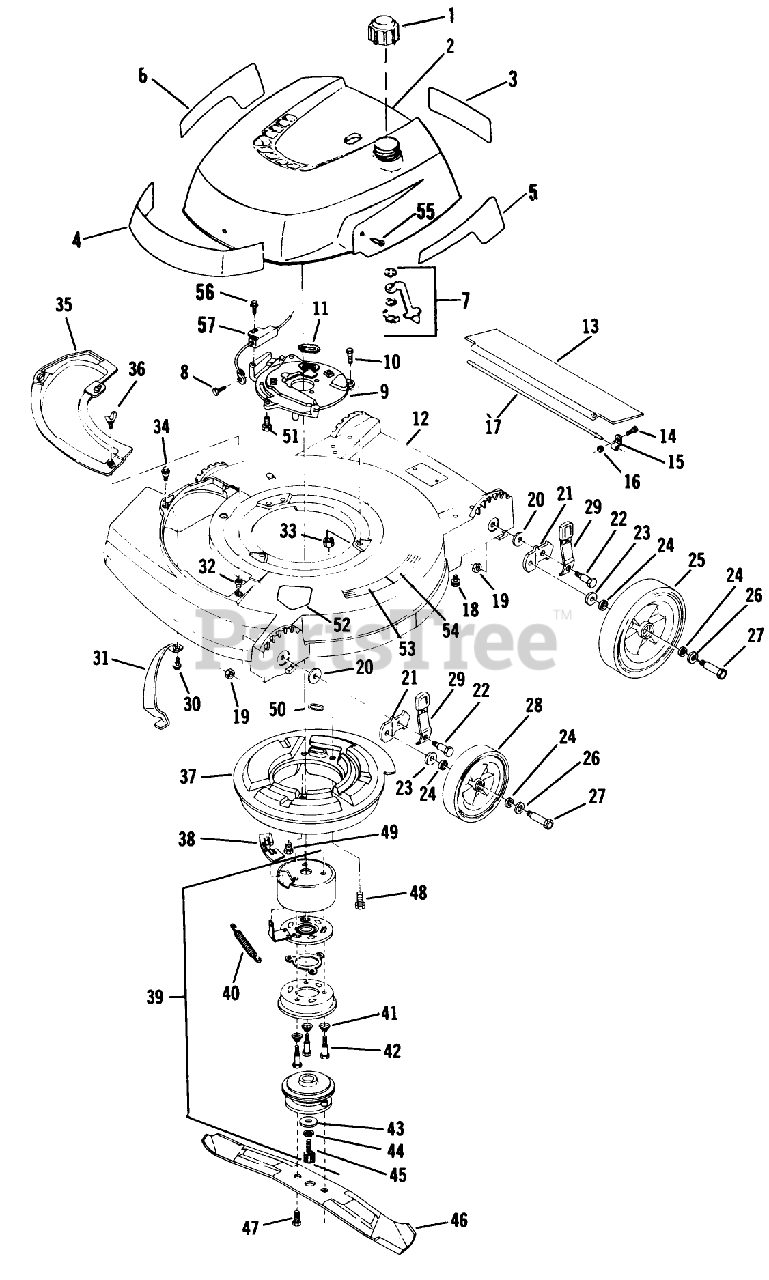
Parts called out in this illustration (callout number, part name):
10	SCREW
15	CLAMP ROD KMC
16	LOCKNUT E
17	ROD 21" ADVANCE
18	SCREW
19	LOCKNUT
20	WASHER
23	WASHER WROUGHT
24	WASHER
26	SPACER
27	BOLT WHEEL
28	WHEEL & TIRE KIT
31	BAR-TOE
33	NUT-LOCK F
36	WING SCREW LAWRE
40	SPRING
42	SCREW,SHOULDER SM
43	WASHER
46	Blade-21"
47	SCREW SEMS
49	SCREW
50	SEAL
51	SCREW V
53	PAD FOOT
55	SCREW S
56	SCREW
